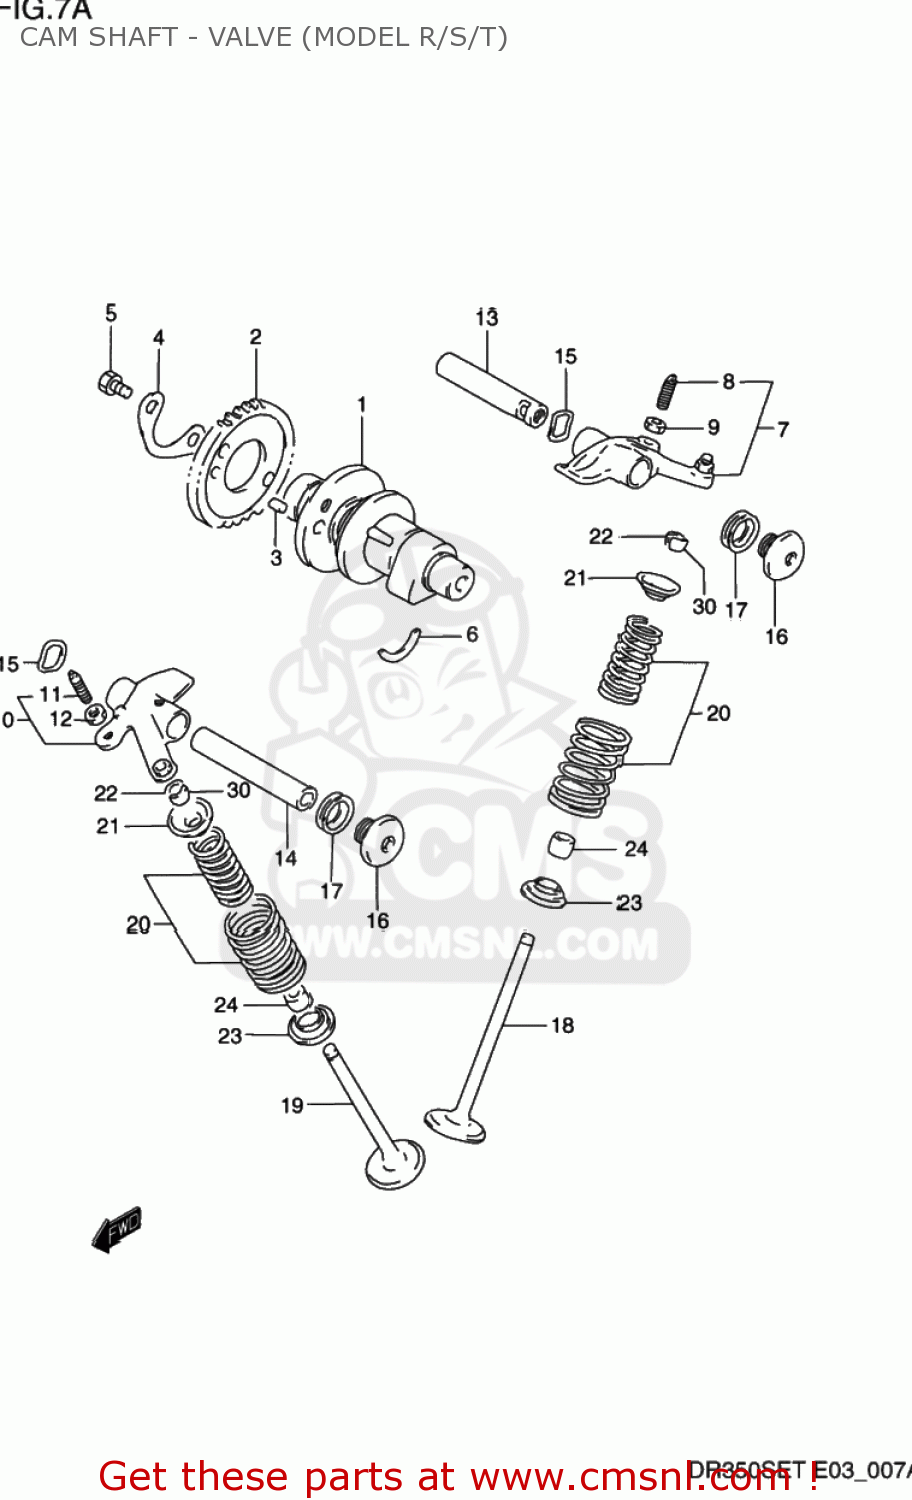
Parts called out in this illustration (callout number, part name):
1	SHAFT COMP,CAM
2	SPROCKET,CAMSHAFT
3	PIN(5X8)
4	WASHER,SPROCKET
5	BOLT(6X10.5)
6	C RING
7	ARM,VALVE ROCKER,INTAKE
8	SCREW,TAPPET ADJUSTING
9	NUT,TAPPET ADJUSTING
10	ARM,VALVE ROCKER EXHAUST
11	SCREW,TAPPET ADJUSTING
12	NUT,TAPPET ADJUSTING
13	SHAFT,VALVE ROCKER ARM INTAKE
14	SHAFT,VALVE ROCKER ARM EXHAUST
15	WASHER
16	PLUG,14X12
17	GASKET(13.8X18.8X4.8) (NAS)
18	VALVE,INTAKE
19	VALVE,EXHAUST
20	SPRING SET,VALVE
21	RETAINER,VALVE SPRING
22	COTTER VALVE
23	SEAT,VALVE SPRING
24	SEAL,OIL(5X10X9.7)
